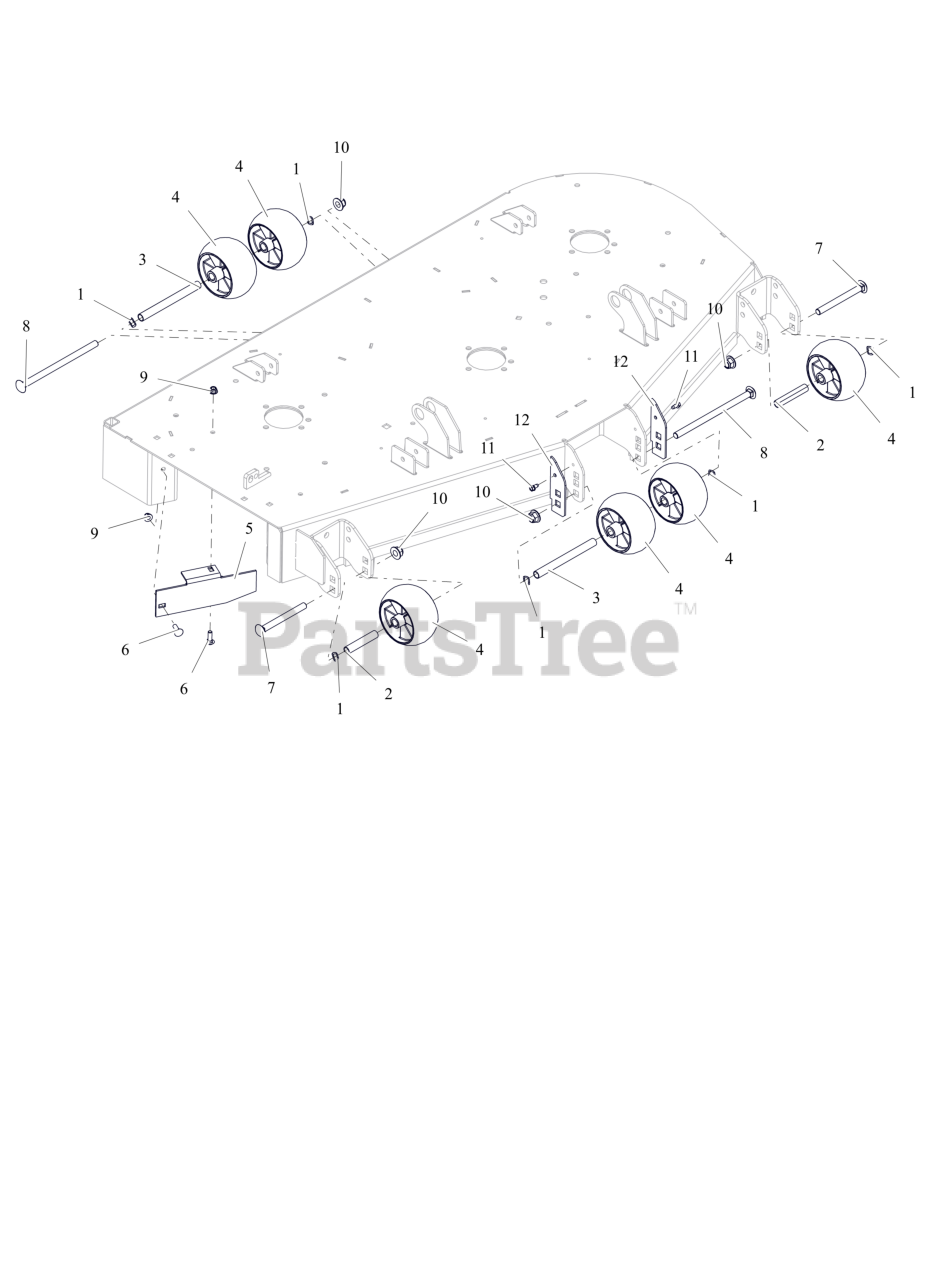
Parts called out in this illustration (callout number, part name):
1	WAVE WASHER .531X.781X.125FH
2	SPACER, .510X.625X3.35
3	SPACER, .510X.625X6.50
4	ANTI-SCALP WHEEL - 5X3 CTR
5	BAFFLE, DISCHARGE, 52"
6	BLT,RHSN .31-18X1.00 G5 ZCC
7	BLT, RHSN .50-13X5.00 G5 ZCC
8	BLT, RHSN .50-13X8.50 G5 ZCC
9	NUT,LK-NYL-FLG .31-18 G5ZC120
10	NUT,NYL-FLG .50-13 GF ZCC
11	SCR-TAP .25-20X.50 HWH ZCC
12	PLATE, ANTI SCALP WHEEL PLATE CE (ORANGE)
